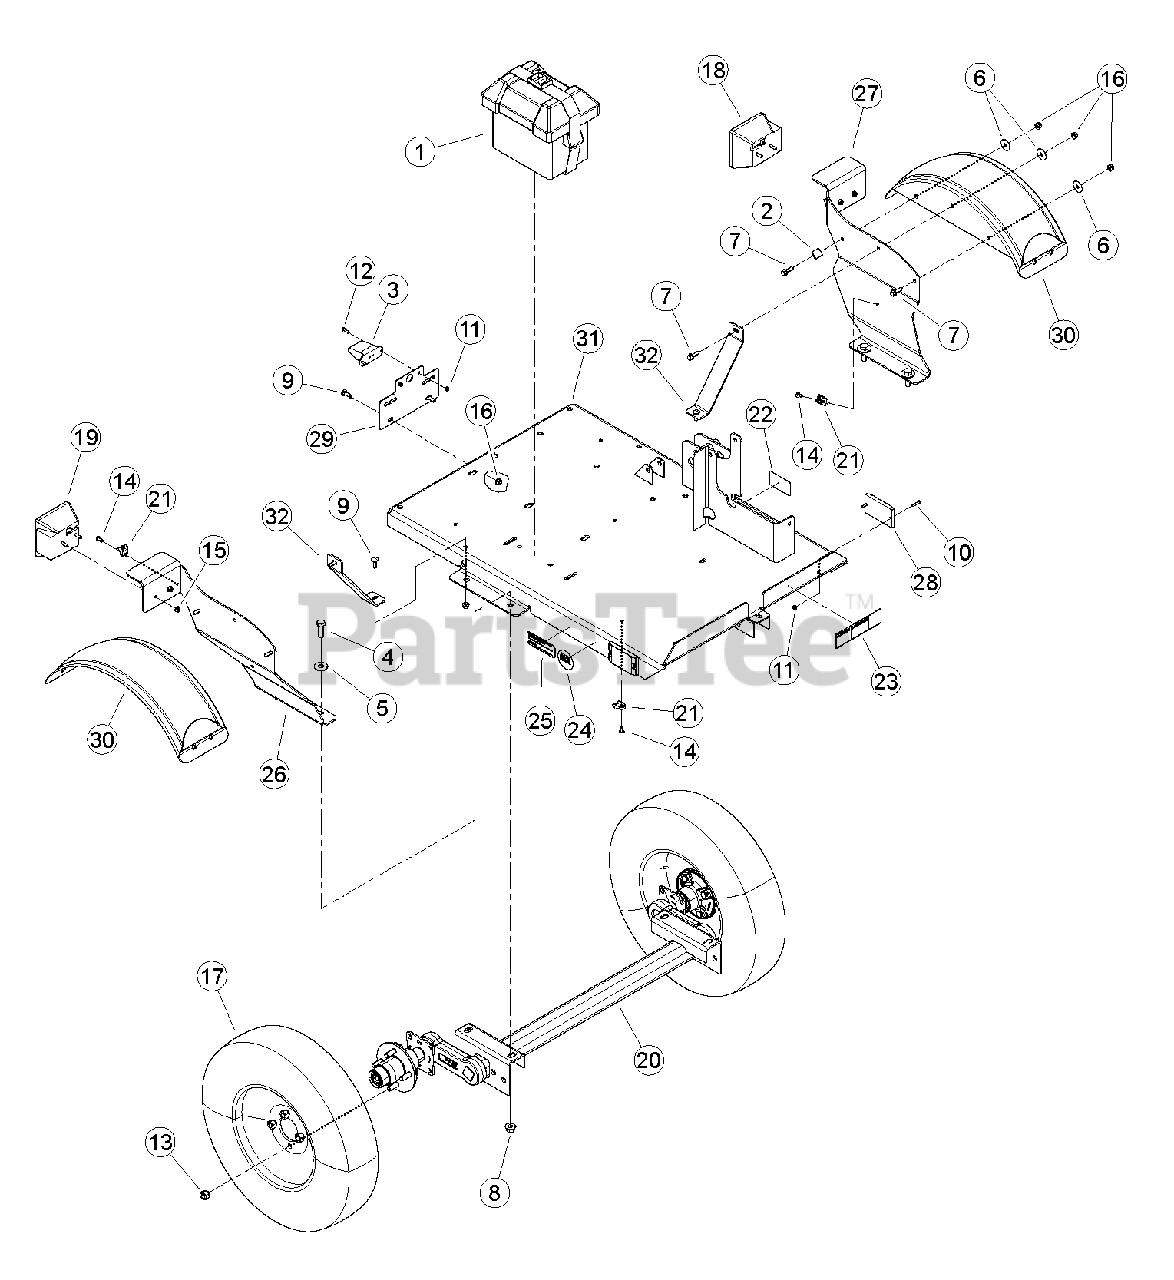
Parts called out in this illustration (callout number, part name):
1	BOX, SMALL BATTERY
2	CLAMP, 9/16 COATED
3	LIGHT, LICENSE PLATE
4	BOLT, 1/2-13 X 1-1/2 HEX HD GR5
5	WASHER, 1/2 FLAT
6	WASHER, 5/16" FENDER ZP
7	BOLT, 5/16 X 1 FLANGE NC
8	NUT, 1/2-13 NYLOCK FLANGE
9	BOLT, 5/16-18 X 1 GR5 CRG
10	SCREW, MCH 10-24 X 1" RND HD PHL ZP
11	NUT, 10/24 NYLOCK TYPE NM ZP
12	SCREW, MCH #10-24 X 3/4" PAN HD PH ZP
13	NUT, 1/2-20 WHEEL
14	RIVET, AL BLIND 1/4 X 3/4 DOME HEAD
15	NUT, 1/4-20 NYLOCK FLANGE
16	NUT, 5/16-18 NYLOCK FLANGE
17	ASSEMBLY, 5.30-12 TIRE + SPOKE RIM
18	LIGHT, LH TAIL
19	LIGHT, RH TAIL
20	AXLE, 1000 LB TORSION
21	CLAMP, CABLE MOUNT
22	DECAL, 5.30-12 LOAD RATING
23	DECAL, CHECK WHEELS
24	DECAL, NATM COMPLIANCE
25	DECAL, EPA EVAP
26	BRACKET, RH FENDER
27	BRACKET, LH FENDER
28	KIT, LED AMBER LIGHT
29	PLATE, LICENSE
30	FENDER, BLACK PLASTIC DRILLED
31	WELDMENT, CHIPPER TRAILER
32	BRACKET, FENDER
